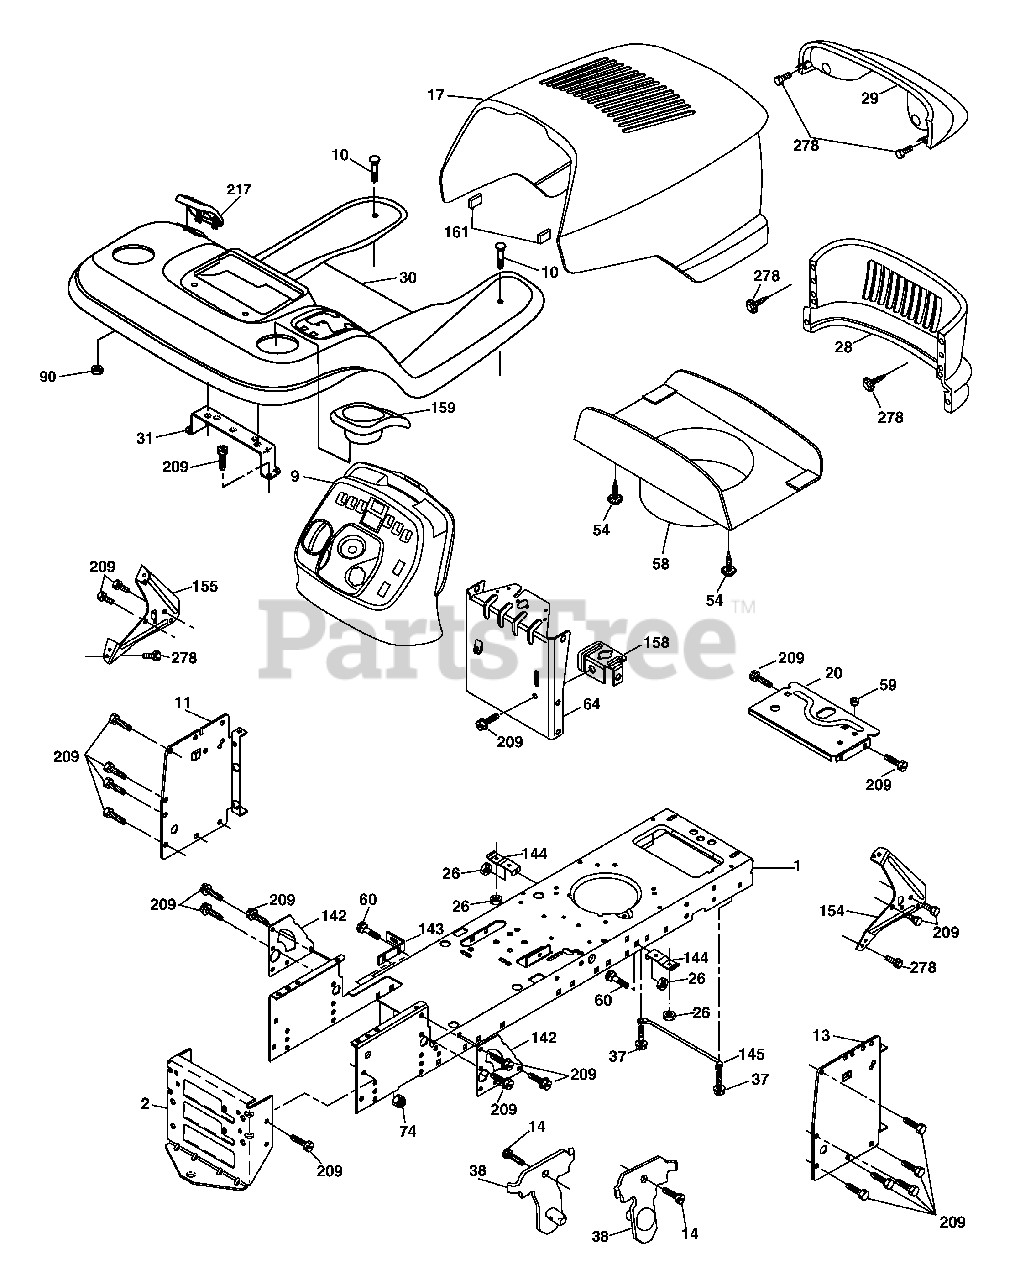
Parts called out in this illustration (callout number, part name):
1	Chassis
2	Drawbar
3	Screw 3/8-16 x 3/4
9	Dash
10	Bolt 3/8-16 x 1
11	Panel Dash Lh
13	Panel Dash Rh
14	Screw Thdrol 3/8-16 x 1/2
17	Hood
20	Plate Battery
26	Nut Lock Hex W/Ins 3/8-16 unc
28	Grille
29	Light Asm. Bar
31	Bracket Fender
37	Screw Thdrol 6/16-18 x 1/2 TYT
38	Bracket, Asm. Pivot Mower Rear
54	Screw Wshd Hex 10-32 x 5/8
58	Duct Hood
59	Bushing Snap
60	Bolt Rd Hd Sqnk 3/8-16 unc x 3/4
64	Dash Lower
74	Nut Crownlock 3/8-16 unc
90	Nut Self-Thd Wsh-Hd 1/4 Zinc
142	Plate Reinforcement STLT
143	Bracket Swaybar Chassis
144	Bracket Footrest
145	Rod Pivot Chassis/Hood
154	Bracket Dash Rh
155	Bracket Dash Lh
158	Bracket Parking Brake
159	Cupholder
161	Extrusion Bumper
209	Screw Hexwsh Thdrol 3/8-16 x 3/4
213	Skirt Grille LH
214	Skirt Grille RH
217	Console Fuel Window
278	Screw 10 x 3/4 Single Lead Hex
